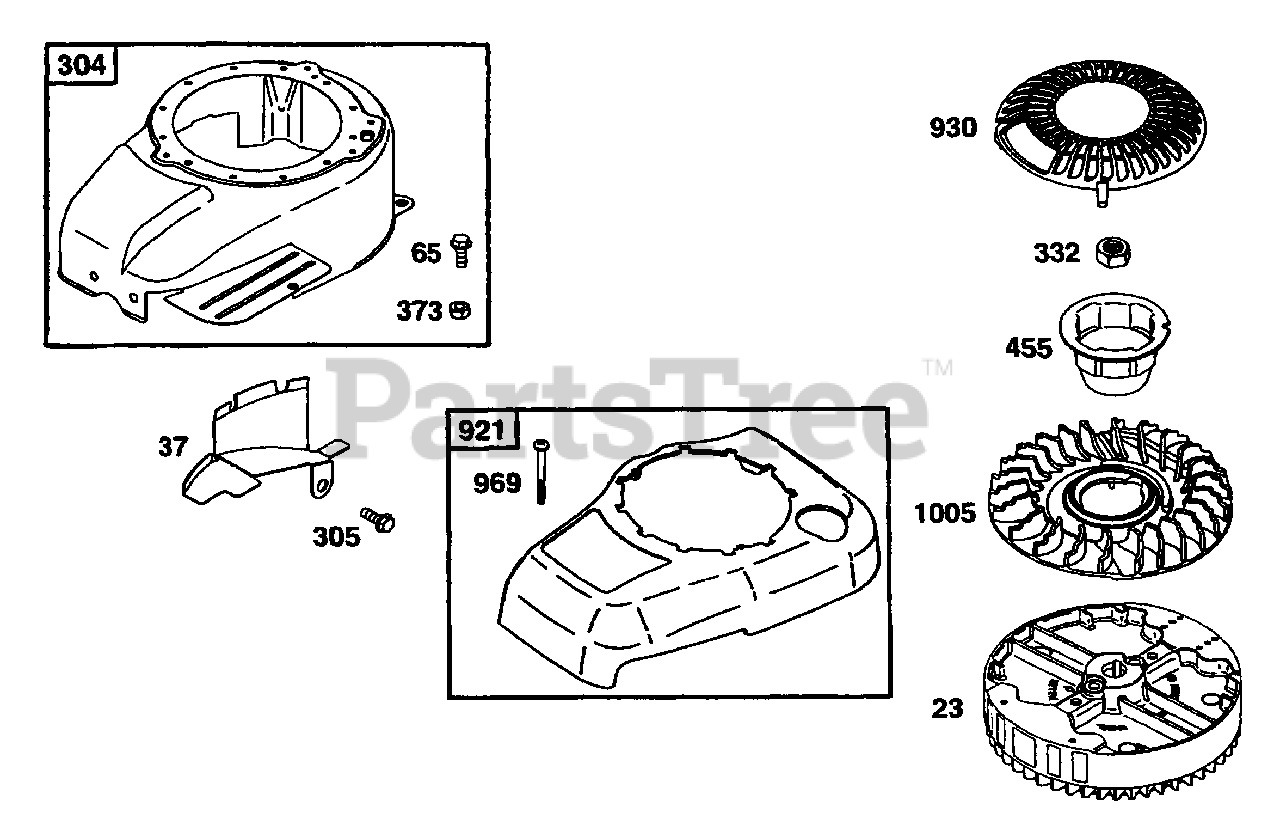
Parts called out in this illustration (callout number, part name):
23	Flywheel
37	Flywheel Guard
65	Hex Screw
304	Blower Housing
305	Hex Screw
332	Flywheel Nut
373	Hex Nut
455	Flywheel Cup
921	Blower Housing Cover
930	Rewind Guard
969	Blower Housing Cover Screw
1005	Flywheel Fan
